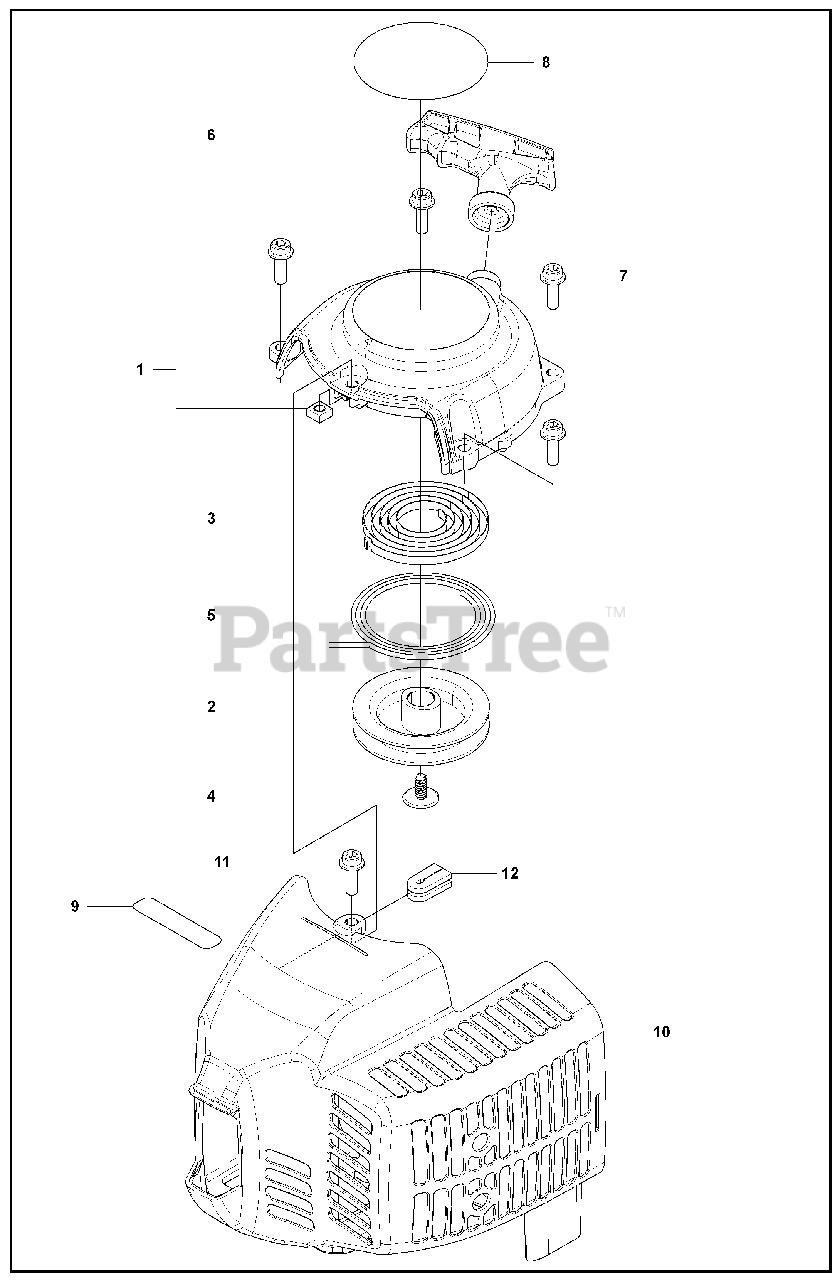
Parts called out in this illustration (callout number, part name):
1	RECOIL ASSY
4	SCREW
7	BOLT TORX
8	LABEL, recoil
8	LABEL, recoil, 226HS99S
9	LABEL, caution
10	COVER, engine
11	BOLT TORX
